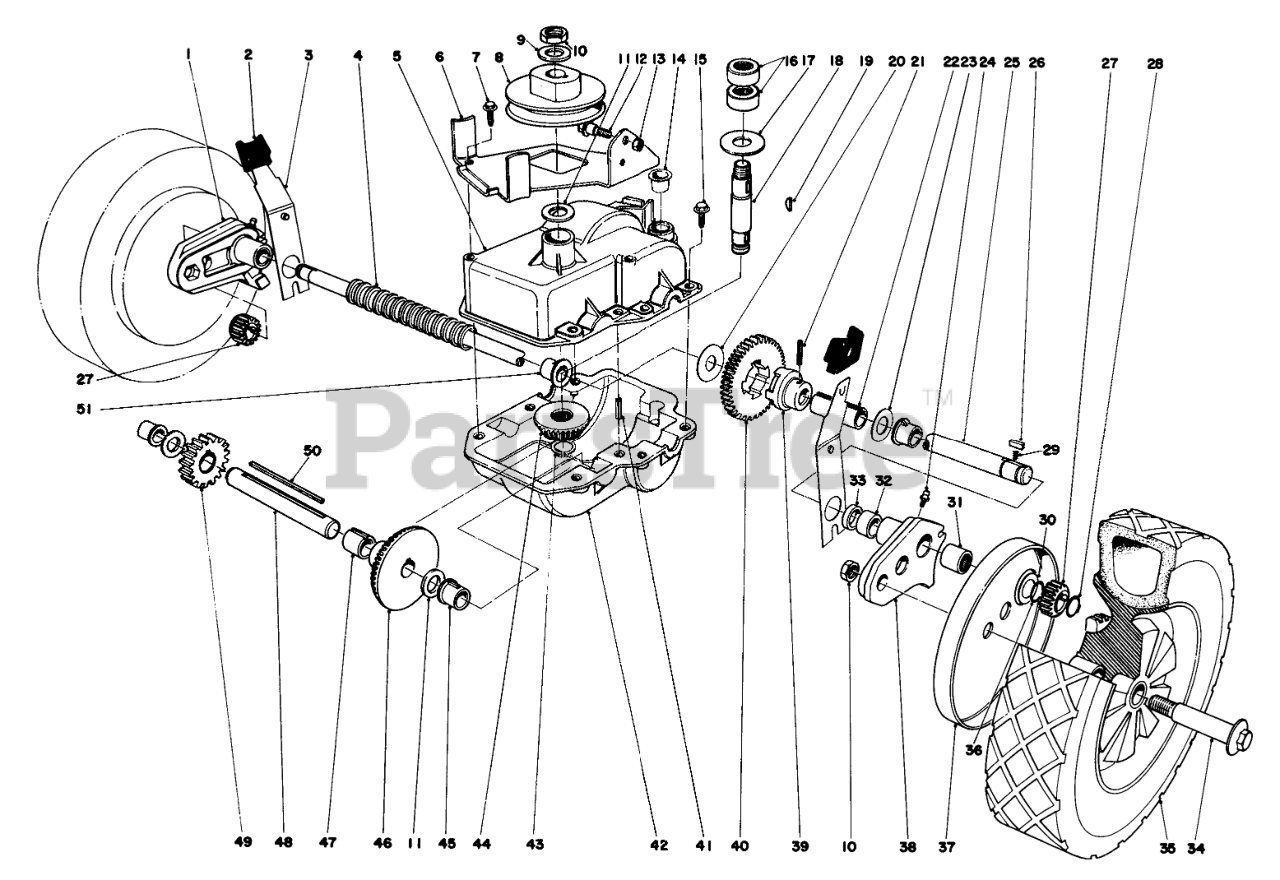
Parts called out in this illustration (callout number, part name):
1	Pivot Arm R.H. (Incl. Ref. #24 & 31-33)
2	KNOB-ARM
3	Spring Arm
4	Cover Drive Shaft
5	Case Upper
6	Bracket-Belt Guide
7	Screw
8	PULLEY
9	Washer
10	Nut
11	WASHER-THRUST
13	BOLT-SHOULDER
14	Caplug
15	SCREW-HWH, THREAD ROLL
16	Bearing
17	Thrust Washer
18	INPUT SHAFT
19	KEY-WOODRUFF
20	WASHER
21	COIL PIN
22	Spacer-Output Shaft
23	WASHER-PLAIN
24	FITTING-GREASE
25	Output Shaft
26	KEY RECTANGULAR
27	GEAR-PINION
28	RING-RETAINING
29	SPRING-COMPRESSION
30	Washer
31	Needle Baring
32	Bushing
33	Seal
34	BOLT-WHEEL
35	Wheel & Tire Assembly
36	RING-EXT GRIP
37	Cover-Wheel
38	Pivot Arm L.H. (Incl. Ref. #24 & 31-33)
39	ADAPTER DRIVE
40	Gear
41	ROLL PIN 3/16 X 1 IN
42	LOWER GEAR CASE CAST
43	RING-RETAINING
44	PINION-BEVEL
45	Botching Shaft
46	BEVEL GEAR
47	Shaft-Pivot
48	Sort Shaft
49	14 T GEAR
50	Key Square
51	Bushing
